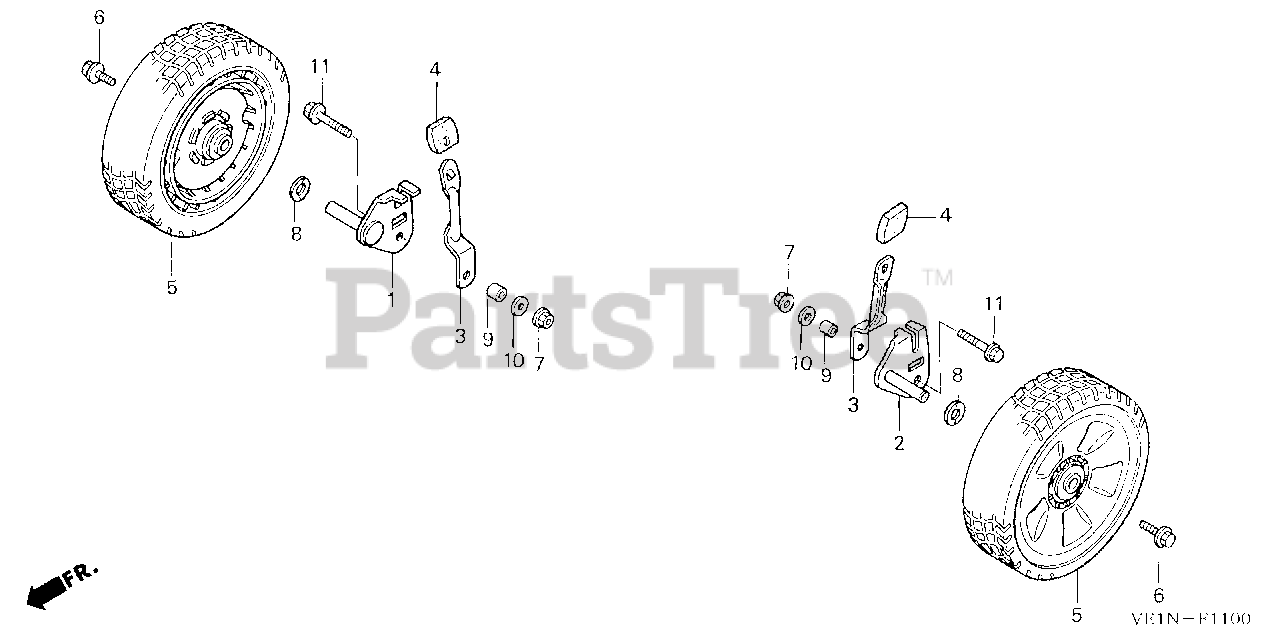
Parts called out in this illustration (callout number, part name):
1	ARM, R. FR. ADJUSTER
2	ARM, L. FR. ADJUSTING
3	PLATE, FR. ADJUSTER
4	GRIP, ADJUSTER
5	WHEEL, FR.
6	BOLT, WHEEL
7	NUT, SELF-LOCK (8MM) (CLINCH)
8	WASHER, WHEEL
9	COLLAR, FR. ARM
10	WASHER, PLAIN (8MM)
11	BOLT, FLANGE (8X50)
